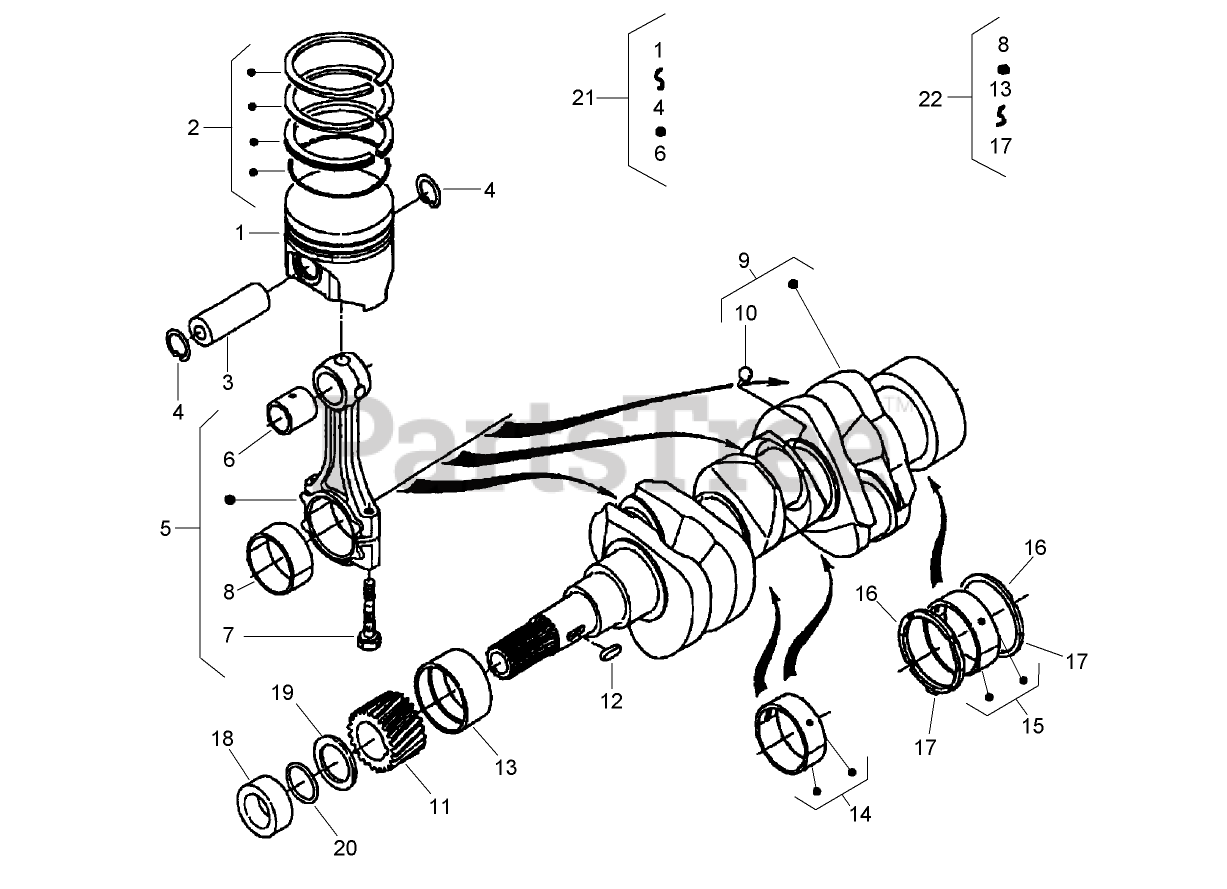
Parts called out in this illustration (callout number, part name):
1	PISTON
2	PISTON RING ASM (STD)
2	PISTON RING ASM (+.25MM)
3	PIN-PISTON
4	CIRCLIP-INTERNAL
5	CONNECTING ROD ASM
6	BUSHING-PIN, PISTON
7	BOLT-ROD, CONNECTING
8	METAL-CRANKPIN (-0.20mm)
8	METAL-CRANKPIN (-0.40mm)
8	METAL-CRANKPIN (STD)
9	CRANKSHAFT
11	GEAR-CRANKSHAFT
12	KEY-FEATHER
13	METAL-CRANKSHAFT (STD)
13	METAL-CRANKSHAFT (-.0.20MM)
13	METAL-CRANKSHAFT (-0.40MM)
14	CRANKSHAFT METAL ASM (STD)
14	CRANKSHAFT METAL ASM (-0.20MM)
14	CRANKSHAFT METAL ASM (-0.40mm)
15	CRANKSHAFT METAL ASM (STD)
15	CRANKSHAFT METAL ASM (-0.20MM)
15	CRANKSHAFT METAL ASM (-0.40MM)
16	METAL-SIDE (STD)
16	METAL-SIDE (+0.20MM)
16	METAL-SIDE (+0.40MM)
17	METAL-SIDE (STD)
17	METAL-SIDE (+0.2MM)
17	METAL-SIDE (+0.4MM)
18	COLLAR-CRANKSHAFT
19	SLINGER-OIL
20	O-RING
21	PISTON KIT (STD)
21	PISTON KIT
22	ENGINE METAL KIT
